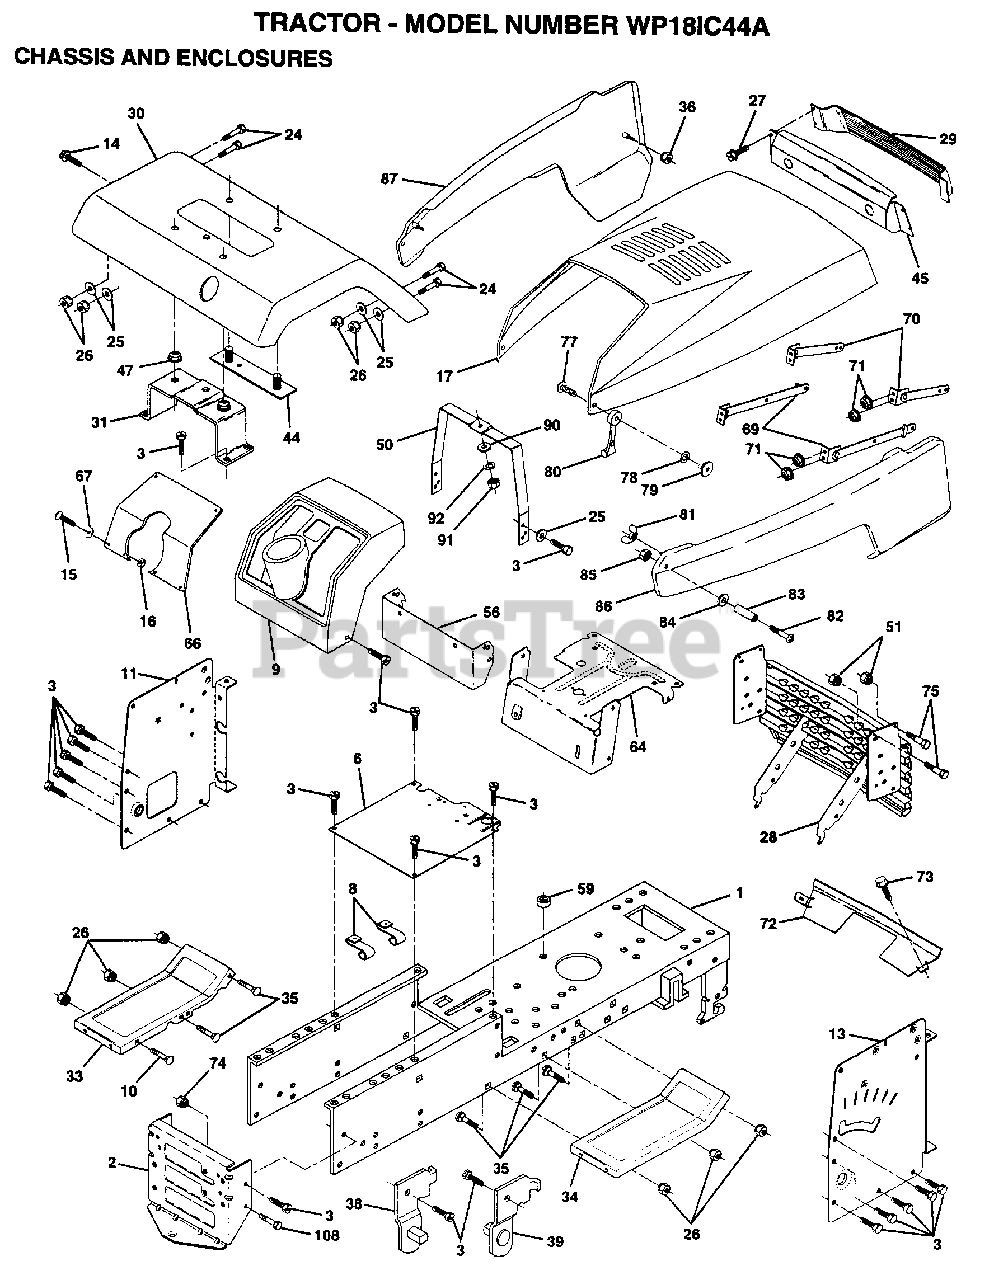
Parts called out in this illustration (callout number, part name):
1	CHASSIS.WLD.11GA
2	DRAW BAR
3	SCREW
8	"CLIP,INSULATOR"
9	DASHBOARD BLACK
11	PANEL.DASH.LH.PNT
13	PANEL.DASH.RH.PNT
14	SCREW LT
15	SCREW
24	BOLT
25	WASHER
26	NUT
29	LENS.BAR.CLEAR
30	FENDER.PNT.
31	BRKT.ASM.FENDER
33	FOOTREST.LH.LT/GT
34	FOOTREST.RH.LT/GT
35	BOLT
36	PAL NUT LT
38	BRACKET ASM LH
39	BRACKET ASM RH
44	STRAP ASM FENDER
47	NUT-PUSH YT
50	DASH.SUPT.YP/HUSQ
51	NUT
56	DASH.EXT.PNT.
66	PLATE SLKSCR YP
67	WASHER
71	NUT HXKEP 1/4X20
72	STRAP.GRILLE.PNT.
73	SCREW CRT
77	SCREW
78	LOCKWASHER
79	WELDNUT
80	HOOD LATCH T
82	SCREW
83	SPACER LT
84	WASHER
86	PANEL SIDE RH
90	WASHER PM
92	LOCKWASHER
